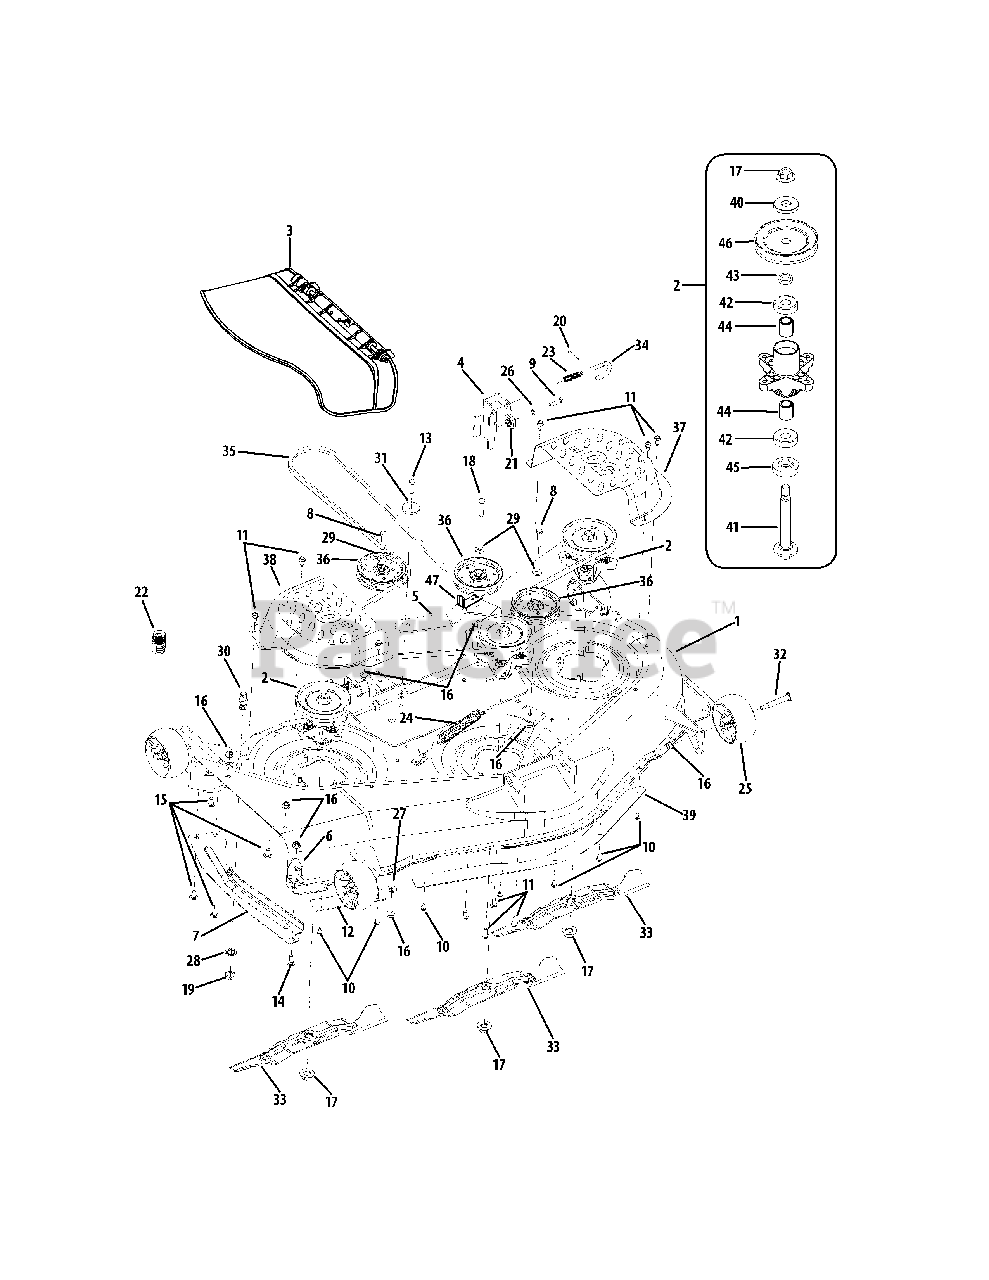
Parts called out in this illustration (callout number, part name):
1	Deck Housing
2	Spindle Assembly
3	Discharge Chute Assembly (U.S.)
4	Deck Hanger Bracket
5	Idler Arm
6	Stop Bracket
7	Finger Guard
8	Hex Cap Screw, 3/8-16 x 1.75
9	Hex Cap Screw, 5/16-18 x 1.25
10	Hex Washer Head Screw, 1/4-20 x .5
11	Hex Washer Head Screw, 5/16-18 x .750
12	RH Skirt
13	Hex Cap Screw, 3/8-16 x 1.25
14	Hex Screw, 3/8-16 x 1.00
15	Carriage Screw, 3/8-16 x .75
16	Hex Insert Flange Lock Nut, 3/8-16
17	Hex Flange Nut, 5/8-18
18	Hex Cap Screw, 3/8-16 x 2.00
19	Hex Nut, M16-1.5
20	Cotter Pin, 1/8 x 1.25
21	Deck Adjustment Gear
22	Water Nozzle Adapter
23	Compression Spring, .535 x 1.751
24	Extension Spring, .94 x 6.74
25	Deck Ball Wheel, 5.0
26	Lock Washer, 5/16
27	Bell Washer, .45 x 1.0 x .062
28	Internal Tooth Lock Washer, 5/8
29	Flat Washer, .38 x .93 x .110
30	Deck Wash Nozzle
31	Shoulder Spacer, .884 x .190
32	Shoulder Screw, .5 x 2.5 x 3/8-16
33	Blade, 2 in 1, 17.9
34	Deck Hanger Rod
35	V-Belt Type A Sec x 134
36	Idler Pulley, 4.25 Dia
37	Belt Cover, LH
38	Belt Cover, RH
40	Flat Washer, .76 x 1.50 x .12
41	Spindle Shaft, 5.75
42	Ball Bearing
43	Spacer, .79 x 1.25 x .175
44	Spacer, .80 x 1.10 x 1.32
45	Spacer, .79 x 1.82 x .55
46	V-Type Pulley, 5.39
47	Bracket, Belt Guard
